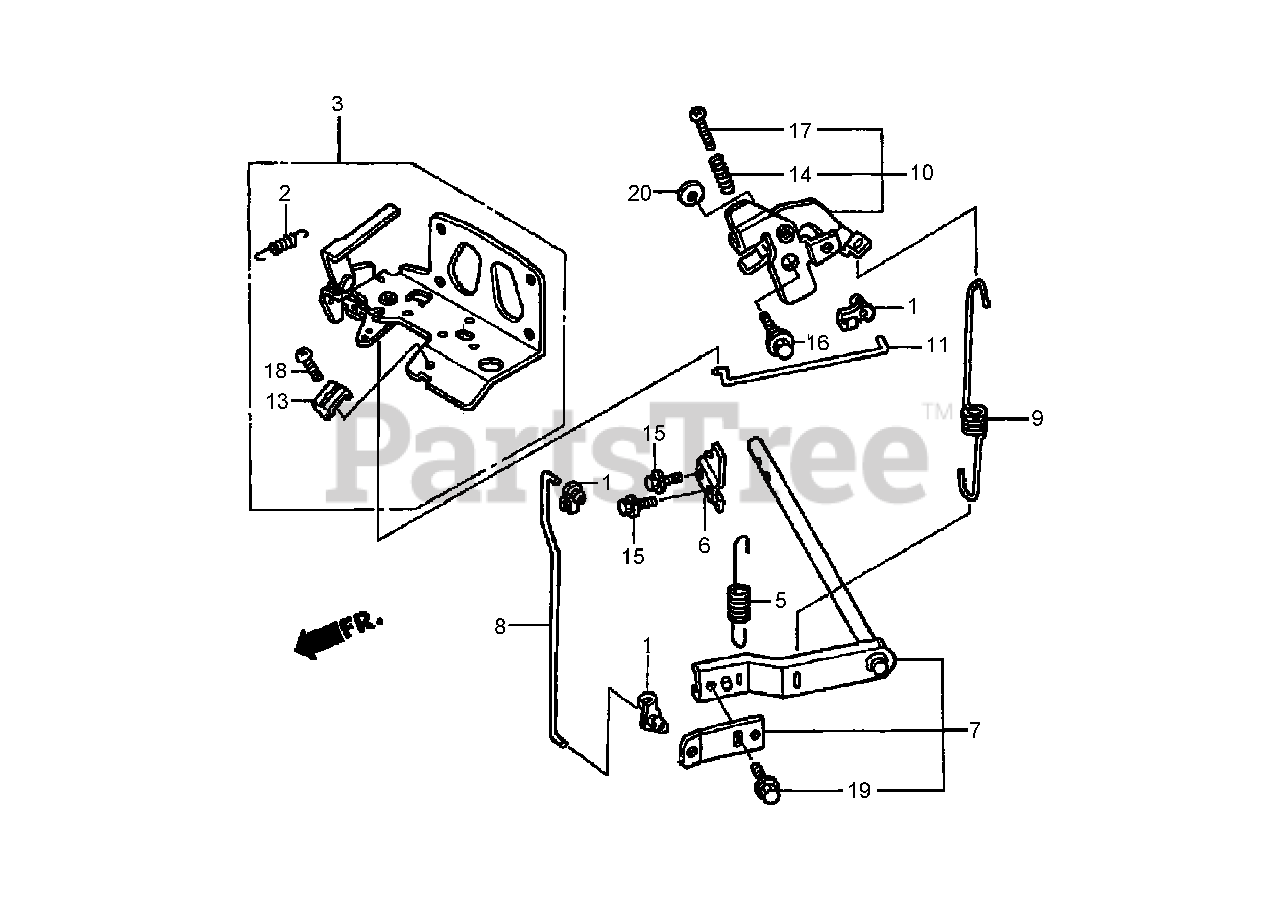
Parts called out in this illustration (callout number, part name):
1	ROD-JOINT
2	SPRING-RETURN, CHOKE
3	CONTROL ASM (1-LEVER)
5	SPRING-STARTER (Up to Engine Serial No. 1014986)
5	SPRING-STARTER (From Engine Serial No. 1038646)
6	FORK-GOVERNOR
7	ARM-GOVERNOR
8	ROD-GOVERNOR
9	SPRING-GOVERNOR
10	LINK-GOVERNOR
11	ROD-LINK, GOVERNOR
13	Holder-Cable
14	SPRING-ADJUSTING, CONTROL
15	BOLT-FLANGE (5X10)
16	BOLT-FLANGE (6MM) (C T200)
17	SCREW-RECESSED (5X25)
18	SCREW-RECESSED (5X18)
19	Bolt-Flange (6X10)
20	WASHER-PLAIN (6MM)
